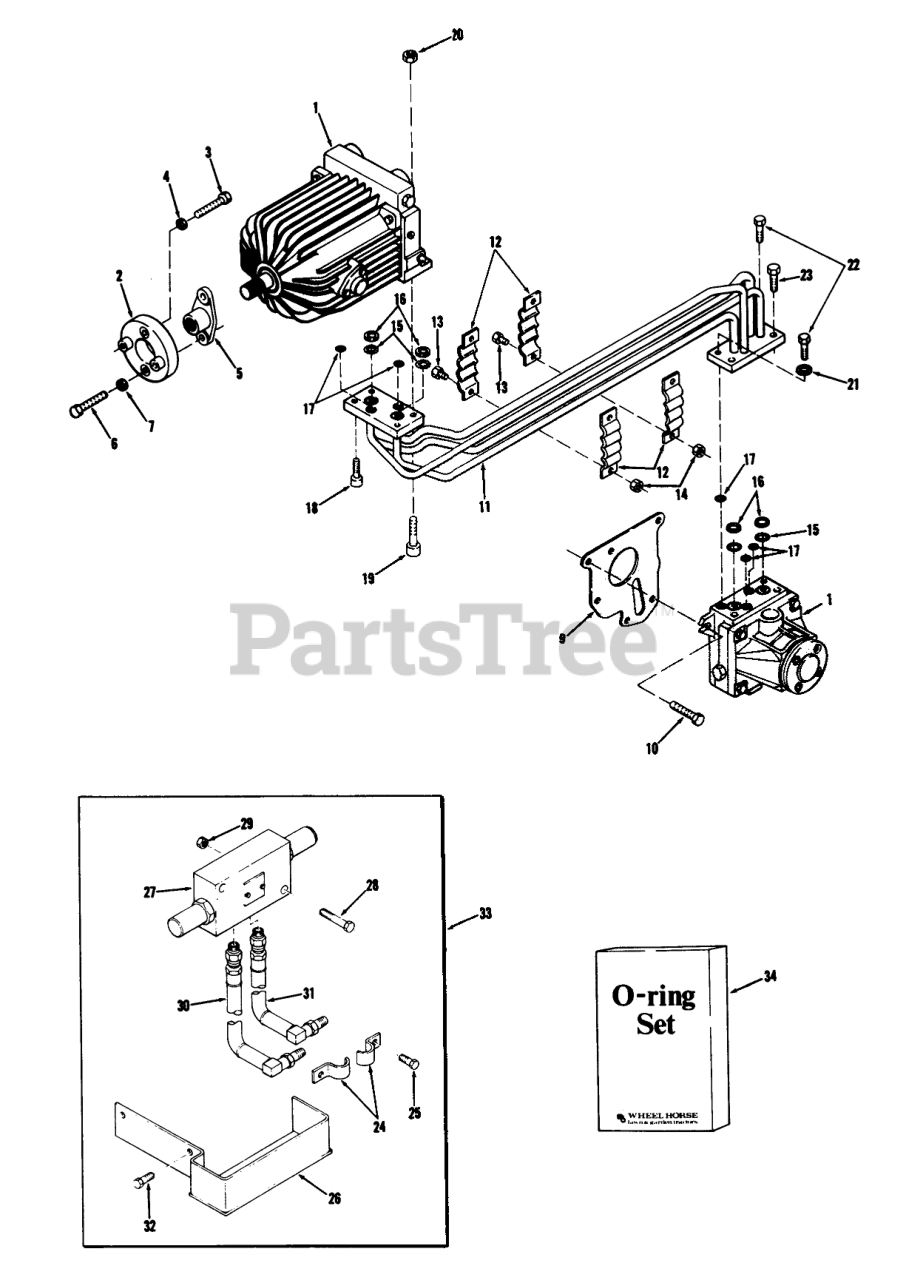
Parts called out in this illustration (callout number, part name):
1	Axle Tube Gasket
2	Coupling
3	Bolt 5/16-18 x 2
3	HHCS
4	Lockwasher
5	COUPLING DRIVEN R
6	Bolt
7	Lockwasher
9	GASKET
10	BOLT
11	Manifold, Hydraulic
12	Clamp
13	Bolt
14	Nut
15	O RING
16	RING BACKUP
17	O RING
18	Bolt
19	Screw
20	NUT
21	SEAL-MANIFOLD BOLT
22	Bolt
23	Bolt 3/8-16 X 1
24	BRACKET
25	Bolt
26	Capscrew
27	Relief Valve
28	Bolt
29	NUT
30	HOSE-HYDRAULIC FRONT
31	ASSY-HYD HOSE FRONT
32	BOLT
33	Relief Valve Kit-S.A.
34	O-Ring Kit-S.A. Incs 15, 16, 17 & 21
